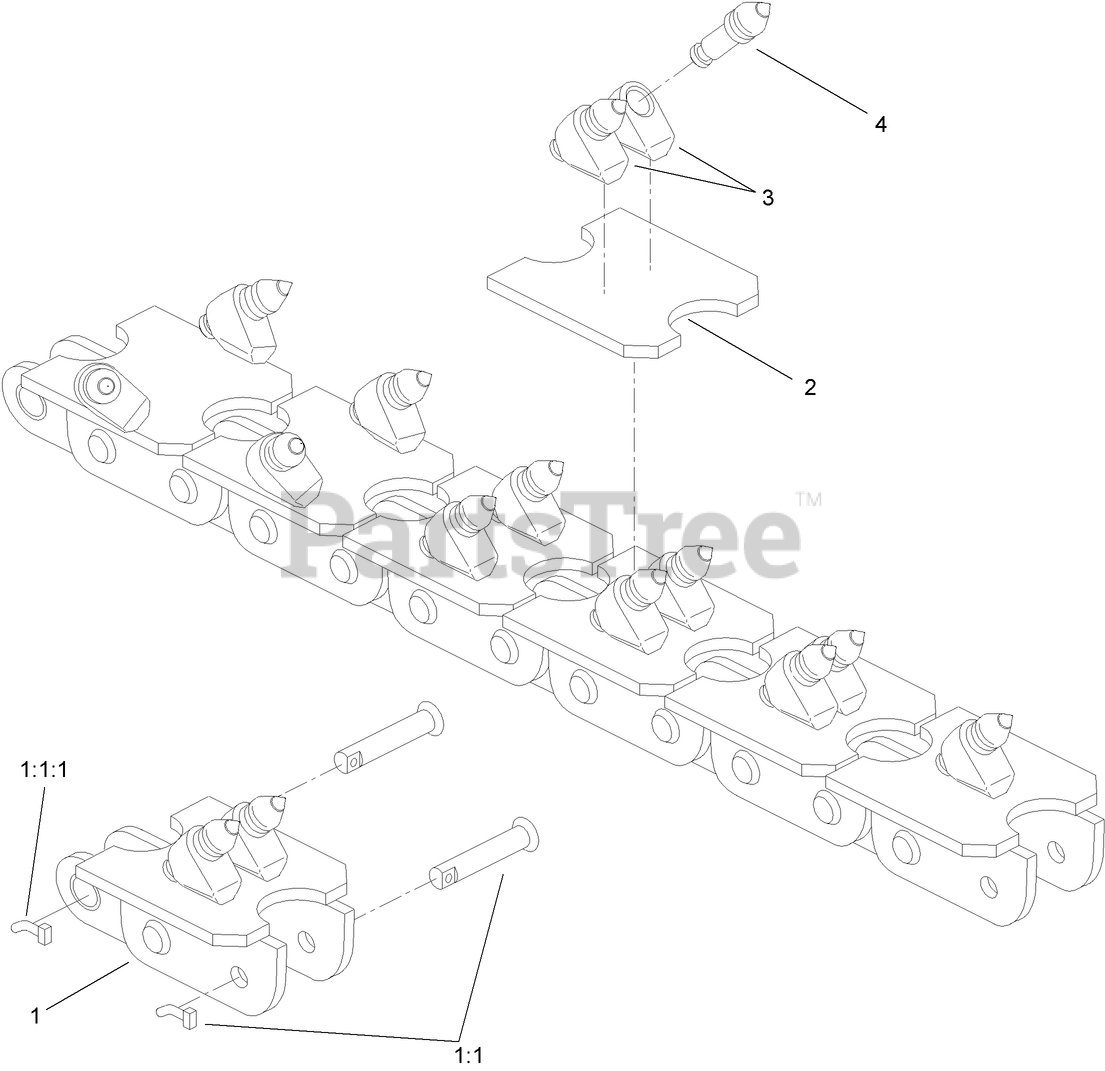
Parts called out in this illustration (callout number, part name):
1	CHAIN REPAIR LINK ASM
1:1	NOTCHED PIN AND KEEPER ASM
1:1:1	PIN-KEEPER
2	PLATE-H, WELD-ON (4 INCH)
3	HOLDER-BIT, WELD-ON
4	BIT-REAR RETAINER, CARBIDE INSERT
